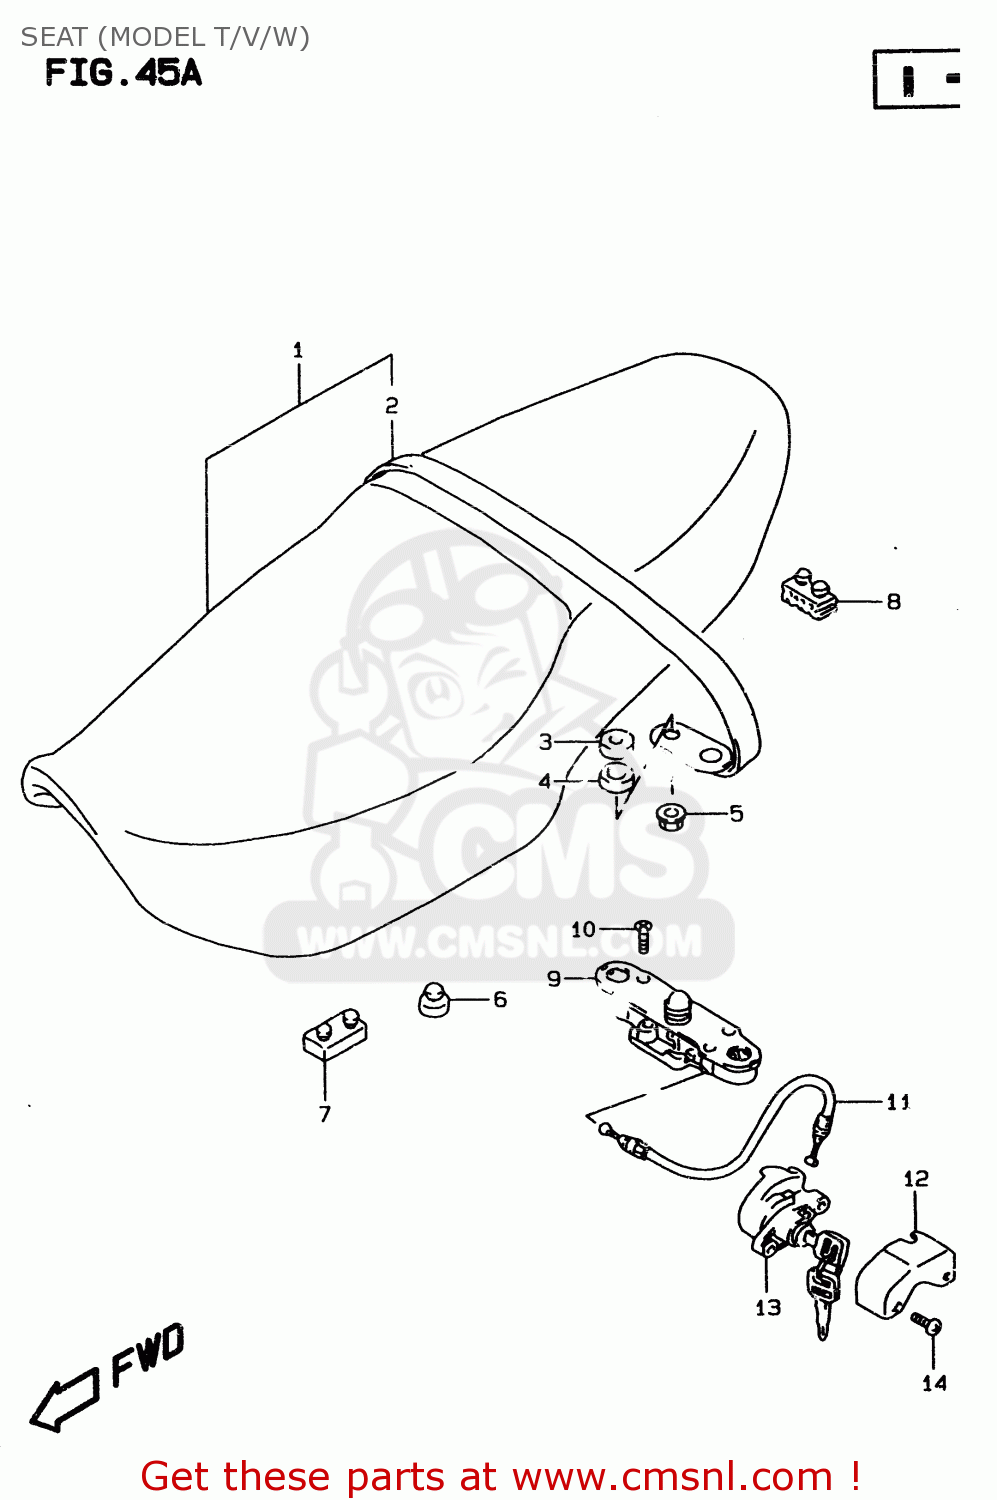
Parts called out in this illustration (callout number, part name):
1	SEAT ASSY
2	BAND ASSY,SEAT(BLACK)
3	CUSHION
4	CUSHION
5	NUT
6	CUSHION
7	CUSHION
8	CUSHION,SEAT(40X20X15)
9	LOCK ASSY,SEAT STRIKER
10	SCREW 6X30
11	CABLE,SEAT LOCK
12	GUARD,SEAT LOCK
13	LOCK SET,SEAT
14	SCREW(6X14)
